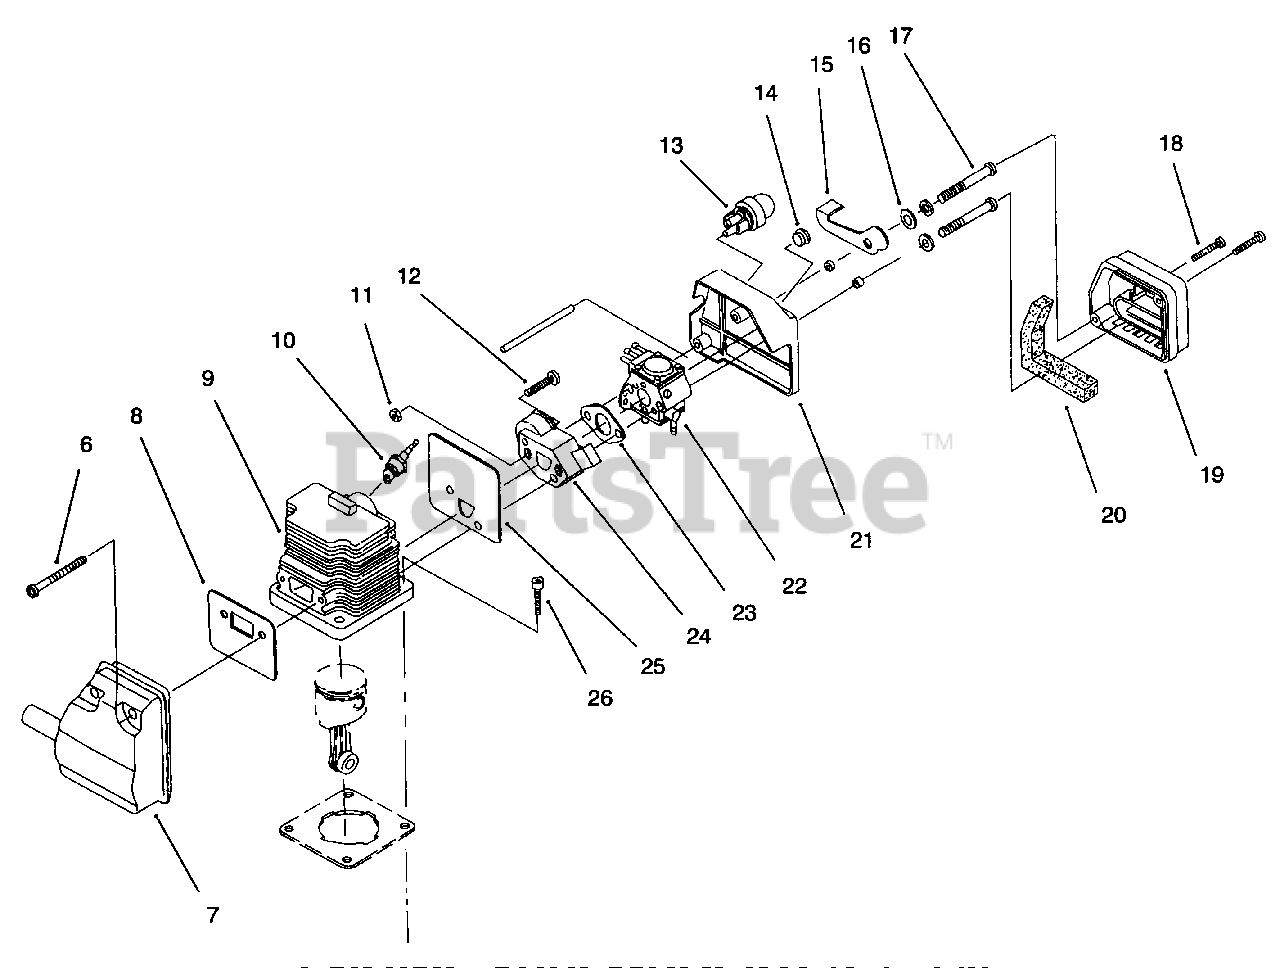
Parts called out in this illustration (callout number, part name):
6	Muffler Mounting Screws
7	Muffler Asm.
8	Muffler Gasket
9	Cylinder
10	Spark Plug
11	Spacer Nut Set
12	Spacer Screw Set
13	Primer Bulb & Hose
14	Plug Switch
15	Choke Lever
16	Wavey Washer
17	Carburetor Mount Screw Asm.
18	Screw
19	Air Cleaner Cover
20	Air Filter Element
21	Air Cleaner Base Asm.
22	Carburetor Asm.
23	Carburetor Gasket
24	Spacer, Carburetor Asm.
25	Cylinder/Carburetor Gasket
